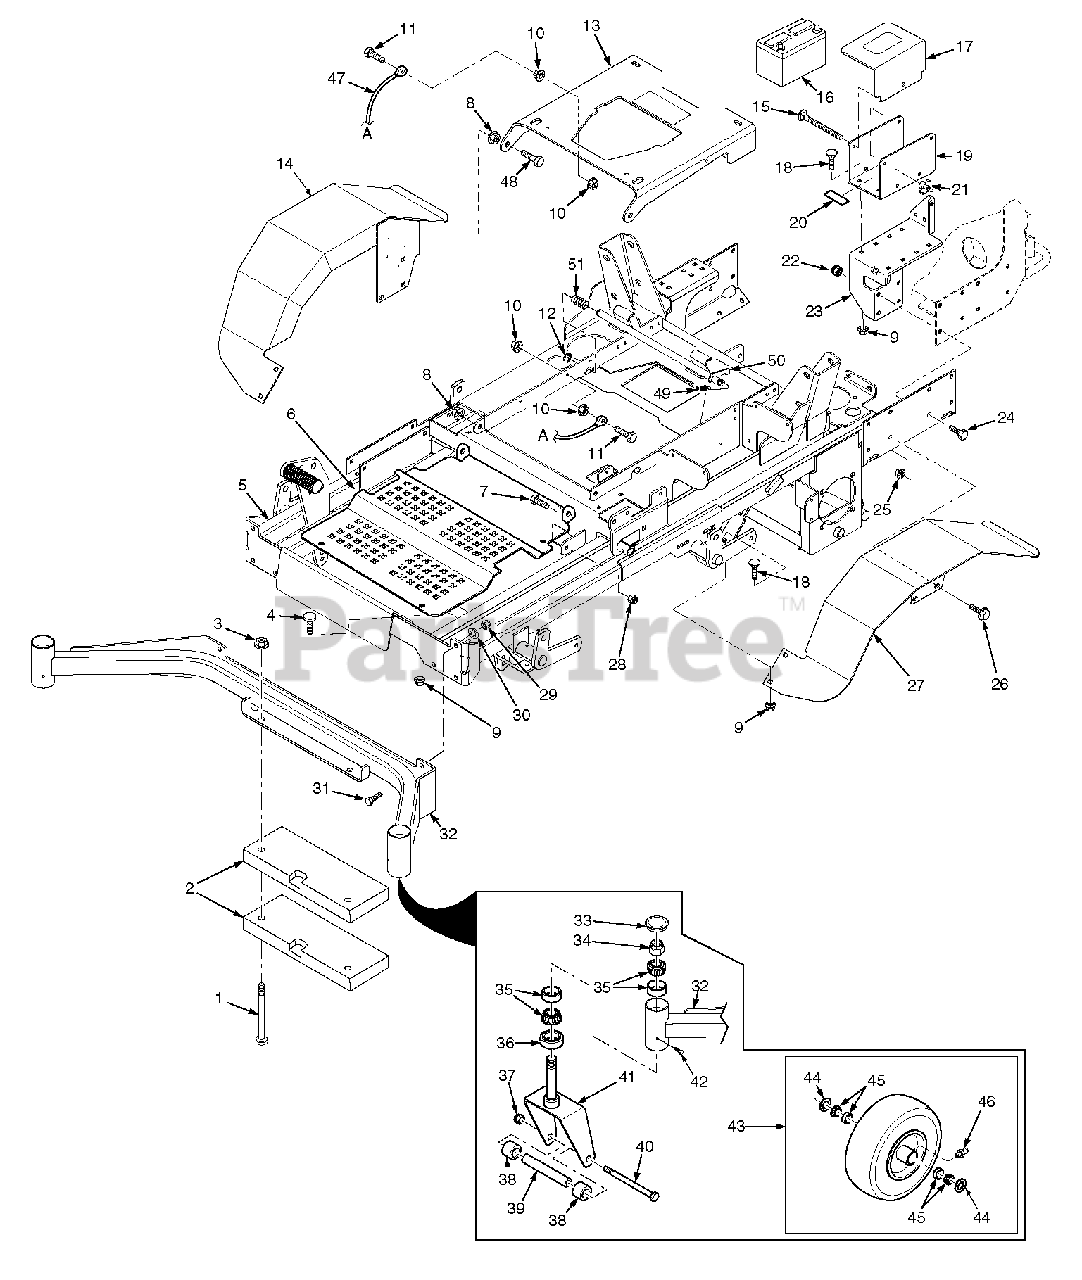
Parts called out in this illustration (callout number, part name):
1	Bolt, Hex Head 1/2-13 x 3.5"
2	Weight
3	Nut, Hex Elastic Stop 1/2-13
4	Bumper, Rubber 5/16-18 x 5/8"
5	Main Frame Assembly w/Decals
6	Foot Plate
7	Bolt, Hex Head 3/8-16 x 1"
8	Nut, Hex Serrated Flange 7/16-14
9	Nut, Hex Serrated Flange 5/16-18
10	Nut, Hex Serrated Flange 1/4-20
11	Bolt, Hex Head 1/4-20 x 1-1/4"
12	Retaining Ring .625" EXT. "E"
13	Seat Plate Weldment w/Decal
14	Fender Weldment, RH
15	Bolt, Carriage 1/4-20 x 6"
16	Battery (not avail. through Scag)
17	Cover, Battery
18	Bolt, Carriage 5/16-18 x 3/4"
19	Plate, Battery Box
20	Rubber Pad
21	Wing Nut, 1/4-20 x 3/4"
22	Nut, Elastic Stop 3/8-16
23	Battery Box Mount
24	Bolt, Hex Head 3/8-16 x 1"
25	Nut, Hex Serrated Flange 3/8-16
26	Screw, Hex Serrated Flange 3/8-16 x 1"
27	Fender Weldment, LH
28	Nut, Hex Elastic Stop 3/8-16
29	Nut, Elastic Stop 7/16-14
30	Lockwasher, 7/16"
31	Bolt, Hex Head 7/16-14 x 1-1/4"
32	Extention Weldment, Caster (Use with 61" Deck)
32	Extention Weldment, Caster (Use with 72" Deck)
33	Cap, Grease
34	Nut, Hex Elastic Stop 1.0"-14
35	Bearing W/Race
36	Seal, 2.00" OD. x 1.625" Bore
37	Nut, Hex Elastic Stop 1/2-13
38	Spacer, Caster Wheel
39	Sleeve, Caster Wheel
40	Bolt, Hex Head 1/2-13 x 9-1/2"
41	Yoke Weldment, Caster
42	Plug, 1/4-28 THD Form
43	Wheel Assembly,
45	Bearing w/ Race
46	Grease Fitting
47	Cable, Seat Stop
48	Bolt, Hex Head 7/16-14 x 1-3/4"
49	Grip, Seat Latch
50	Lever Assembly, Seat Release
51	Spring, Seat Latch
